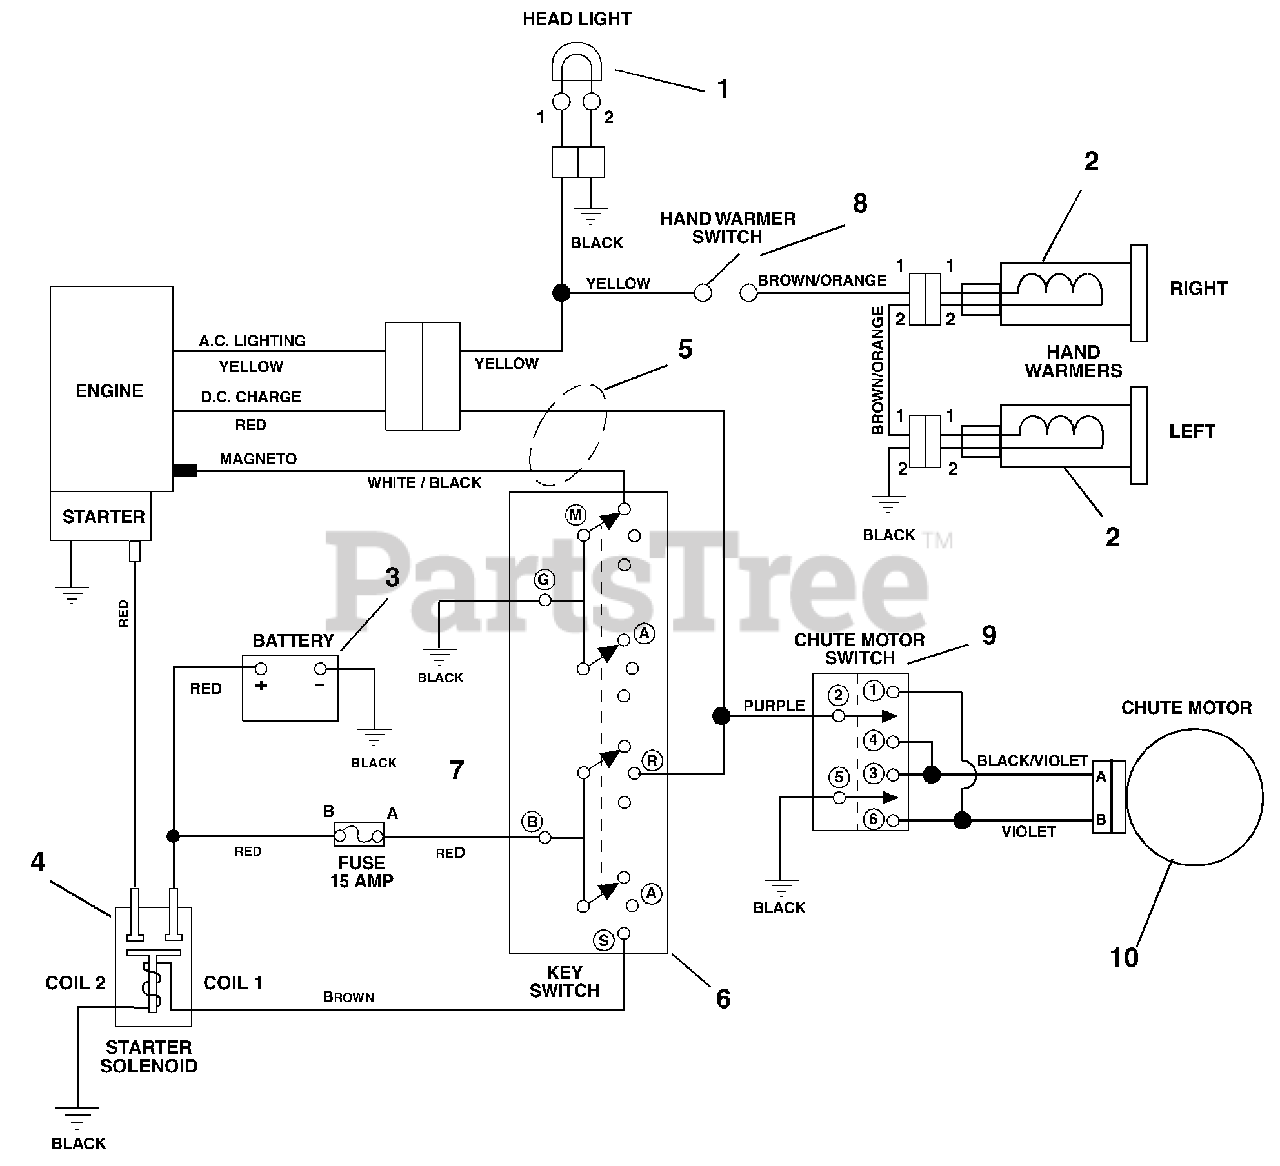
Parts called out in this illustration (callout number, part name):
1	HEADLAMP, OVAL W/ 1156 BULB
2	WARMER, HAND W/TERMINAL
3	Battery
4	SOLENOID
5	HARNESS, WIRE COMP.
6	SWITCH ASSEMBLY
7	FUSE, 15 AMP.
8	SWITCH, ON/OFF
9	SWITCH, CHUTE ROTATION
10	MOTOR, ELECTRIC R.H. - CHUTE
